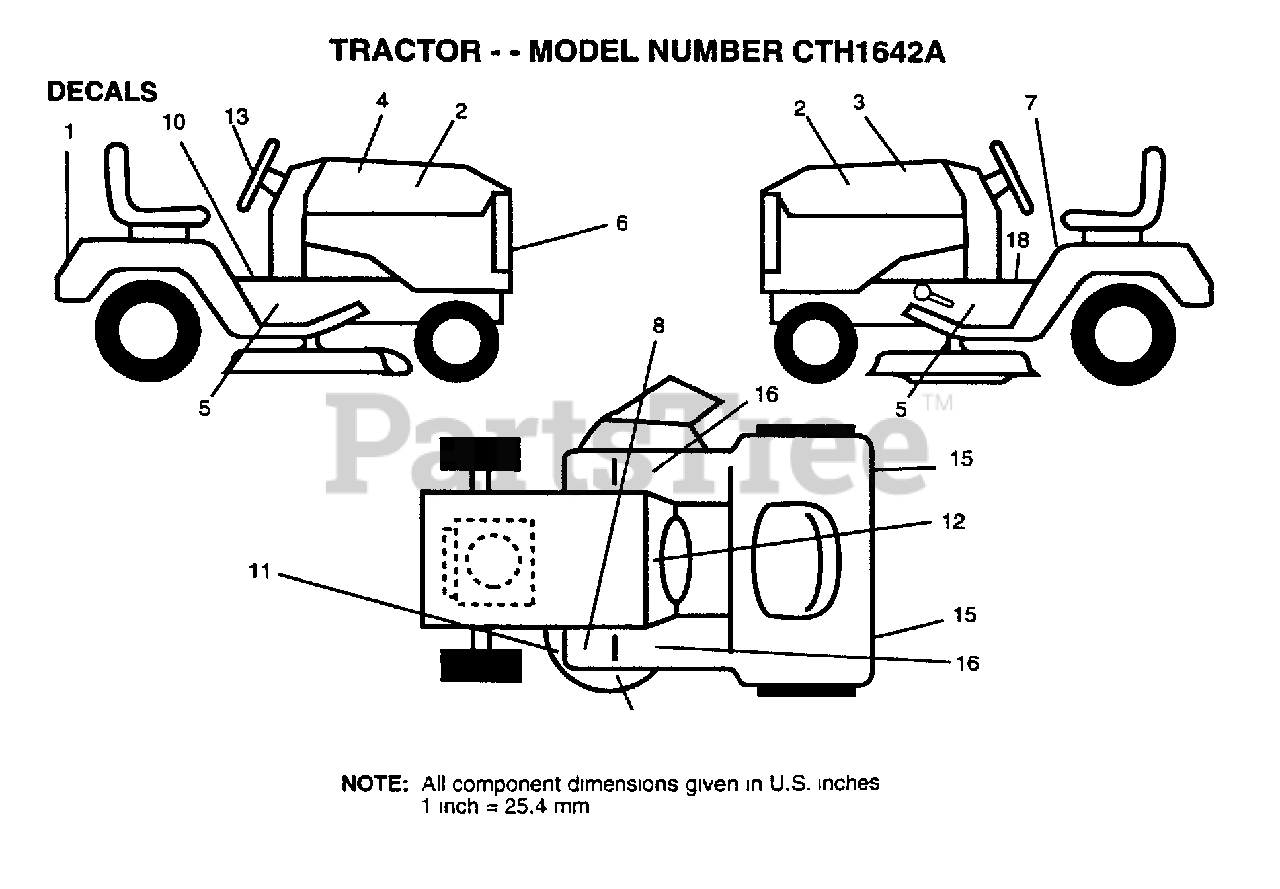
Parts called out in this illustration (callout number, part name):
1	DECAL.FENDER
2	DECAL.HD.INS.
3	DECAL.HOOD.LH.
4	DECAL.HOOD.RH.
5	DECAL CHAS 42 HYD
6	DECAL.GRILLE
7	DECAL
10	DECAL BRAK PARK
11	DECAL
12	DECAL.DASH.INST.
13	DECAL INST STRWHL
15	REFLECTOR-TAIL YT
16	FOOTREST PAD
18	DECAL SADLE HYDRO
